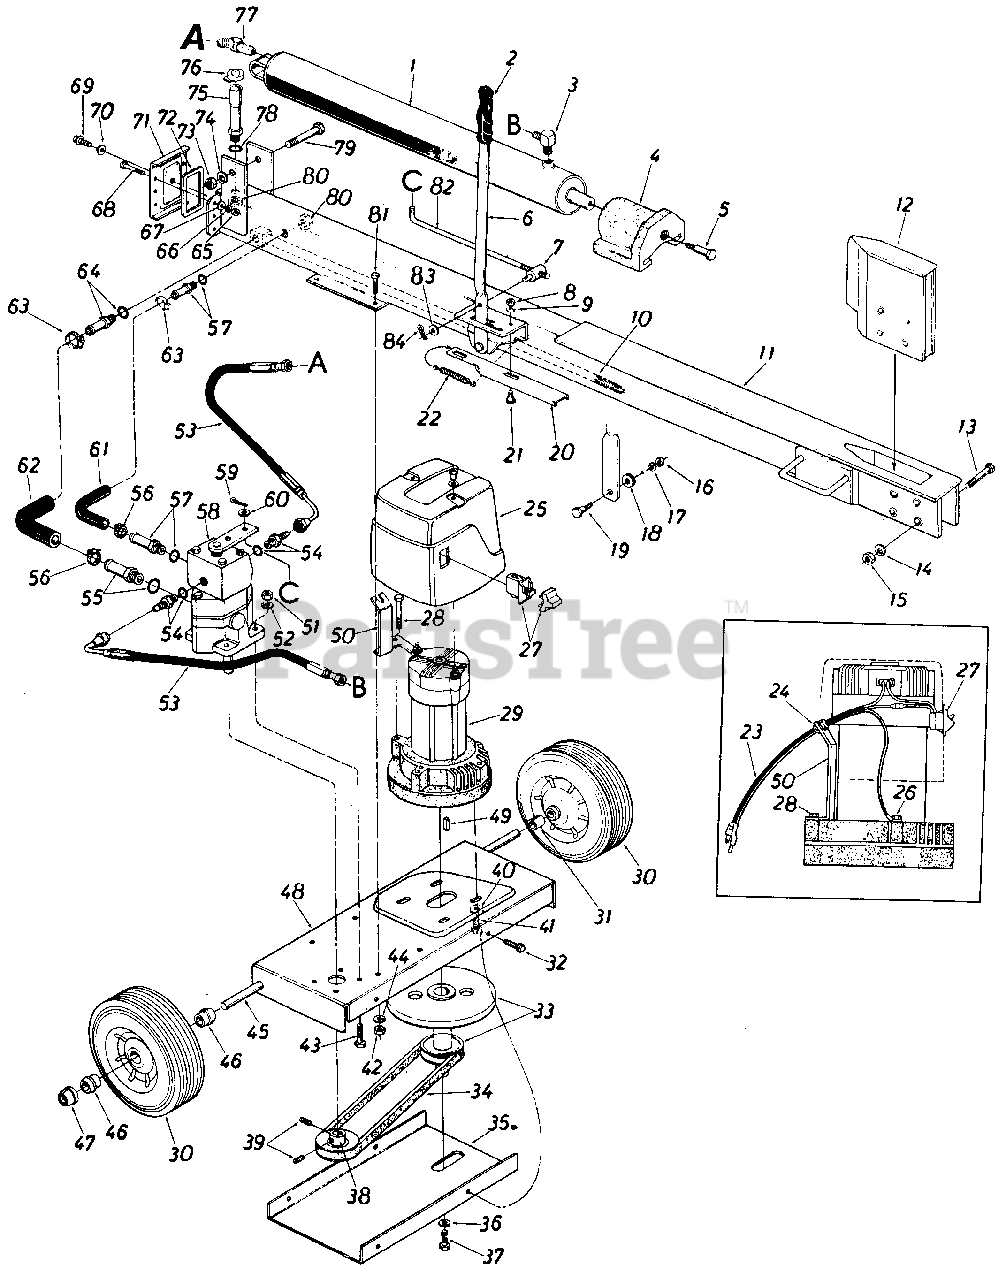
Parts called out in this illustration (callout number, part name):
1	2-1/2" Cyl. Ass'y. Comp.
2	Grip
3	90ø Elbow Adapter
4	Pusher Plate
5	Shoulder Bolt 5/8" Dia. x .660" Lg. 1/2-13 Thd.
6	Engagement Handle
7	Adjustment Ferrule
8	Hex Nut 5/16-18 Thd.*
9	L.-Wash. 5/16" I.D.*
10	Strainer Tube Ass'y.
11	Oil Tank Ass'y. Comp.
12	Wedge Ass'y.
13	Hex Bolt 5/8-18 x 3.50" Lg. Grade 5
14	L.-Wash. 5/8" I.D.*
15	Hex Nut 5/8-18 Thd.*
16	Hex Nut 3/8-16 Thd.*
17	L.-Wash. 3/8" I.D.*
18	Rubber Wash.
19	Shou Ider B olt .498 x .340
20	Engagement Brk't.
21	Shoulder Bolt .437" Dia. x .180" Lg.
22	Extension Spring .50" O.D. x 4.25" Lg.
23	Cord with Plug
24	Cord Restraint
25	Motor Shroud
26	Hex Wash. Hd. Scr. 8-32 x .38" Lg. (Green)
29	Electric Motor
30	Wheel Ass'y. Comp. 10.0" x 2.75
31	Sleeve .632" I.D. x .875" O.D. x .90" Lg.
32	Hex Wash. Hd. Self Tap. Scr. 1/4-20 x . 50" Lg.
33	Motor Pulley & Flywheel Ass'y.
34	"V"-Belt (4L) 1/2" V x 29" Lg.
35	Belt Cover
36	L.-Wash. 5/16" I.D.*
37	Hex Bolt 5/16-24 x .75" Lg. Grade 5
38	1/2 (4L) "V"-Pulley 5/8" I.D. x 3-1/2" O.D.
39	SetScr. 1/4-28 x .25" Lg.
40	Bell.-Wash. .345" I.D. x .88" O.D.
41	Hex Bolt 5/ 1 6-1 8 x . 50" Lg.*
42	Hex Nut 5/ 16-24 Thd.*
43	Hex Bolt 5/16-18 x 1.00" Lg.*
44	L.-Wash. 5/16" I.D.*
45	Axle Shaft 5/8" Dia. x 25.5" Lg.
46	Flange Brg. w/Flats .631" I.D.
47	Push Cap 5/8" Dia. Rod
48	Frame-Motor
49	Sq. Key 3/16" x 3/16" x 1.50" Lg.*
50	Restraint Bracket
51	Hex Nut 5/16-18 Thd.*
52	L.-Wash. 5/16" I.D.*
53	High Pressure Hose
54	Adapter-or Boss to MJIC 9/16-18 to 7/16-20
55	Adapter 3/4" Tubing to 3/4-16 M Boss
56	Hose Clamp 5/8" I.D.
57	Adapter 1/2" Tube 9/16-18 or M Boss
58	Valve Ass'y.
59	Cotter Pin 3/32" Dia. x .75" Lg.*
60	Fl.-Wash. .344" I.D. x .62" O.D. x .063
61	Return Hose.50" I.D.
62	Suction Hose .75" I.D.
63	Hose Clamp 1/4" I.D.
64	Adapter 1.0" Tube 1-1/16--12 "0"-Ring
65	Hex Nut 5/16-18 Thd.*
66	L.-Wash. 5/16" I.D.*
67	Fl.-Wash. .343" I.D. x .687" O.D. x .062
68	Hex Bolt 5/16-18 x 1.50" Lg.*
69	Hex Hd. Tap Scr. 5/16"
70	Gasket
71	End Plate
72	Gasket
73	Hex Nut 3/4" Thd.*
74	L.-Wash. 3/4" I.D.*
75	Filler Tube Ass'y.
76	Oil Fill Cap
77	45ø Male Adapter 7/16-20 MJ-1/4-18 NP
78	"O"-Ring.92" I.D. x 1.16" O.3. x .116 Dia.
79	Hex Bolt 3/4" x 4.0" Lg.
80	Hex Nut 11/16-12 Thd.
81	Hex Bolt 5/16-24 x 1.00" Lg. Grade 5
82	Engagement Rod 16.75" Lg.
83	Fl.-Wash. .344" I.D. x .62" O.D. x .063
84	Hair Pin Cotter5/16" Dia.
